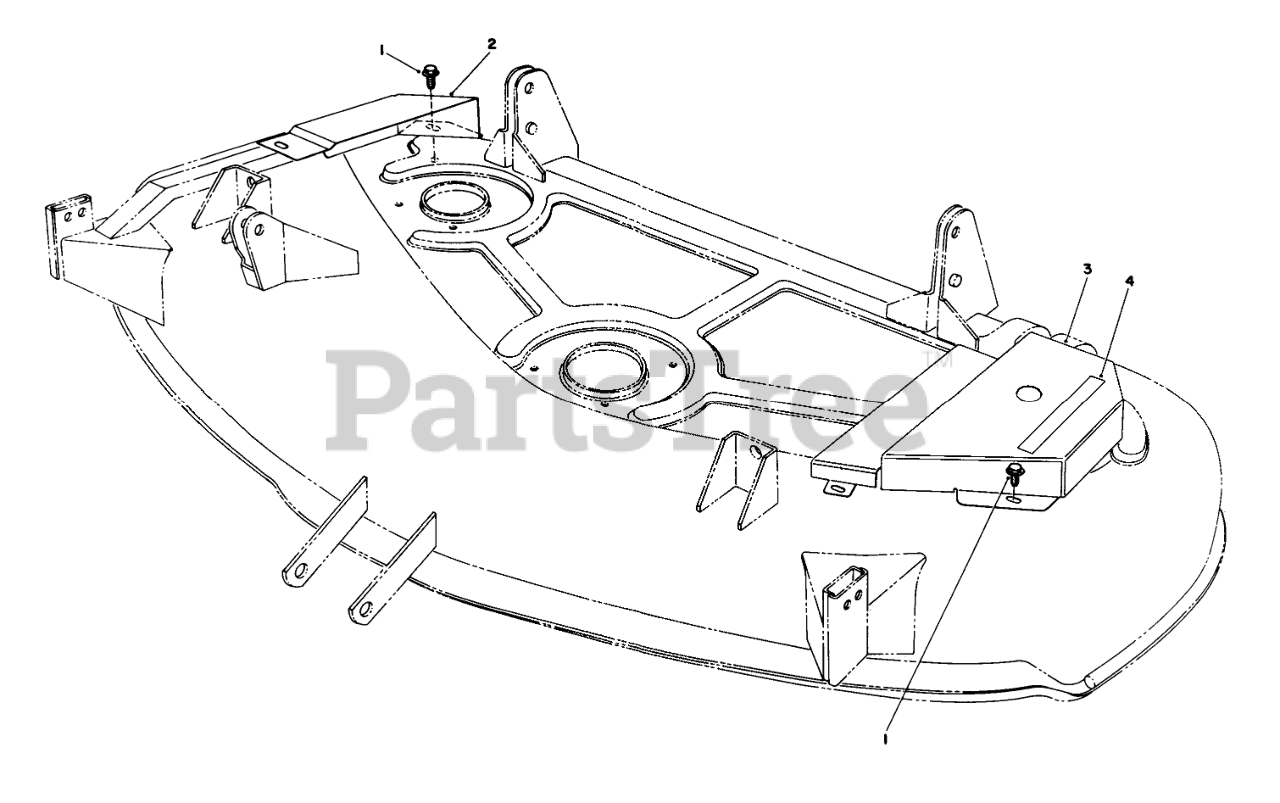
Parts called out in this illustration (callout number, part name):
1	SCREW-HHFTF
2	R/H COVER B
3	Cover-LH
4	DECAL-NO STEP
